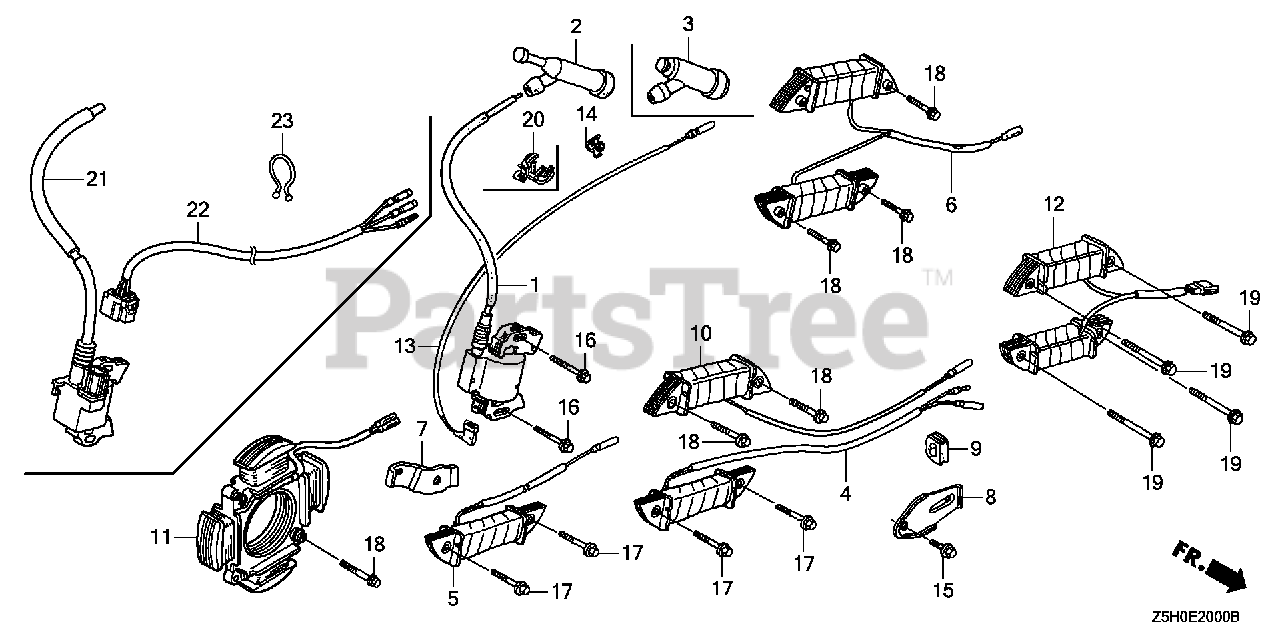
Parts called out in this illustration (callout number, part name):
1	COIL ASSY., IGNITION
3	CAP ASSY., NOISE SUPPRESSOR
8	CLAMP, WIRE
9	GROMMET, WIRE
10	COIL ASSY., CHARGE (1A)
13	WIRE, STOP SWITCH (370MM)
15	BOLT, FLANGE (6X12) (CT200)
16	BOLT, FLANGE (6X28) (CT200)
18	BOLT, FLANGE (6X28) (CT200)
